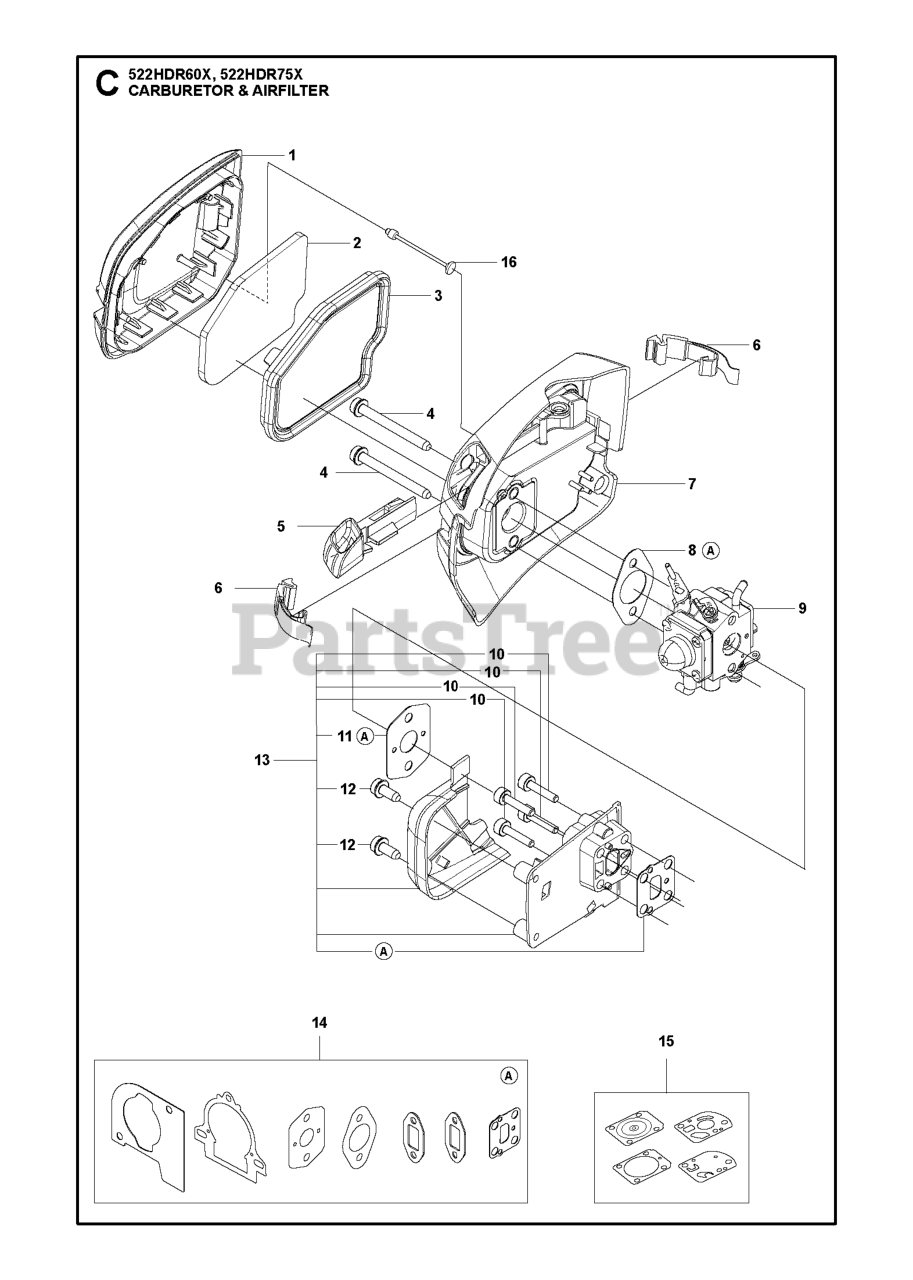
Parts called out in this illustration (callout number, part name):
1	FILTER COVER AGILE
2	AIR FILTER FOAM AGILE
3	FILTER FELT AGILE
7	FILTER HOLDER ASSY AGILE
9	CARBURETTOR CARBURETTOR ASSY
12	SCREW ITXSCFT MT5X12 T27 10.9
13	MANIFOLD 522X
14	GASKET KIT 522
15	KIT CARBURETTOR A053
